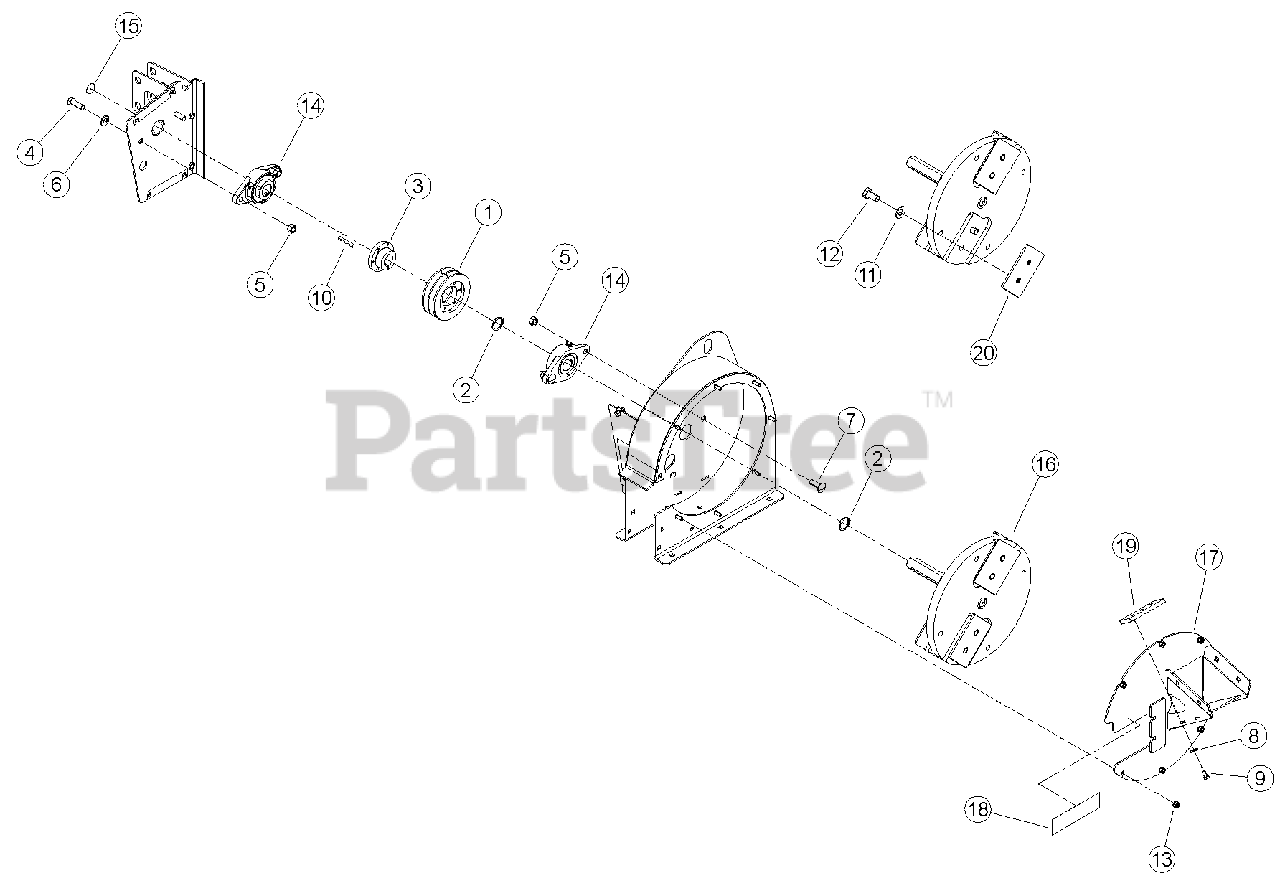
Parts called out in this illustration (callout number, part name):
1	SHEAVE, 2B4.8 SDS
2	SNAP RING, 1-1/4 EXT. HEAVY DUTY
3	BUSHING, SDS 1-1/4"
4	BOLT, 1/2 X 1-1/2" HEX HD GR5 ZP
5	NUT, 1/2" CENTERLOCK GRB ZP
6	WASHER, 1/2" SAE FLAT ZP
7	BOLT, 1/2 X 1-1/2 CRG SN GR5 ZP
8	WASHER, 5/16" FLAT ZP
9	BOLT, 5/16 X 5/8 GR5 HEX CPS ZP
10	KEY, 1/4 SQ X 2" PLAIN
11	WASHER, 5/8 SAE HARDENED
12	BOLT, M16 X 2.0 X 30 HEX HD W/ PATCH
13	NUT, 5/16-18 NYLOCK FLANGE
14	BEARING, 1-1/4" DIA 2 BOLT FLANGE
15	DECAL, ROTATING SHAFT
16	WELDMENT, 4-1/2 PTO DISK
17	ASSEMBLY, DISK COVER, SERVICE PART
18	DECAL, ECHO BEARCAT 6.82 X 1.90
19	ANVIL, CHIPPER
20	KIT, 4-1/2 CHIPPER BLADE (1/2")
